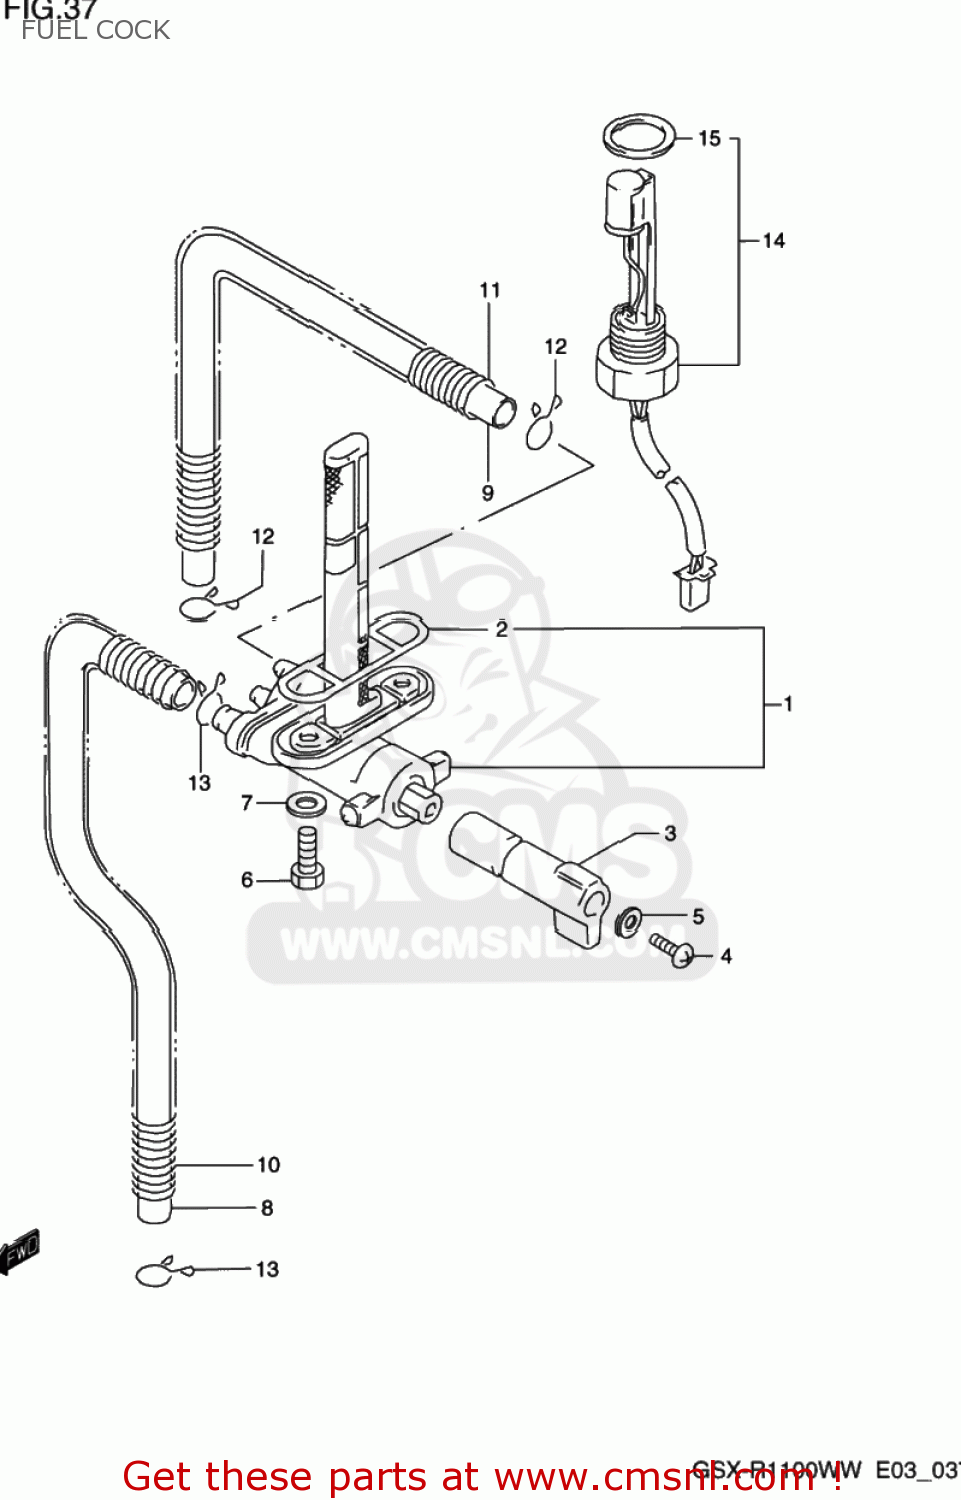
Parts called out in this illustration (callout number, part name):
1	COCK ASSEMBLY,FUEL
2	O RING,FUEL TANK JOINT
3	LEVER,FUEL COCK
4	SCREW
5	WASHER,LOCK
6	BOLT(6X20)
7	GASKET(6.4X11.5X0.8) (NAS)
8	HOSE(7X10.2X600)
9	HOSE(7X10.2X600)
10	SPRING
11	SPRING
12	CLIP
13	CLIP
14	GAUGE ASSY,FUEL LEVEL
15	GASKET,FUEL LEVEL GAUGE (NAS)
